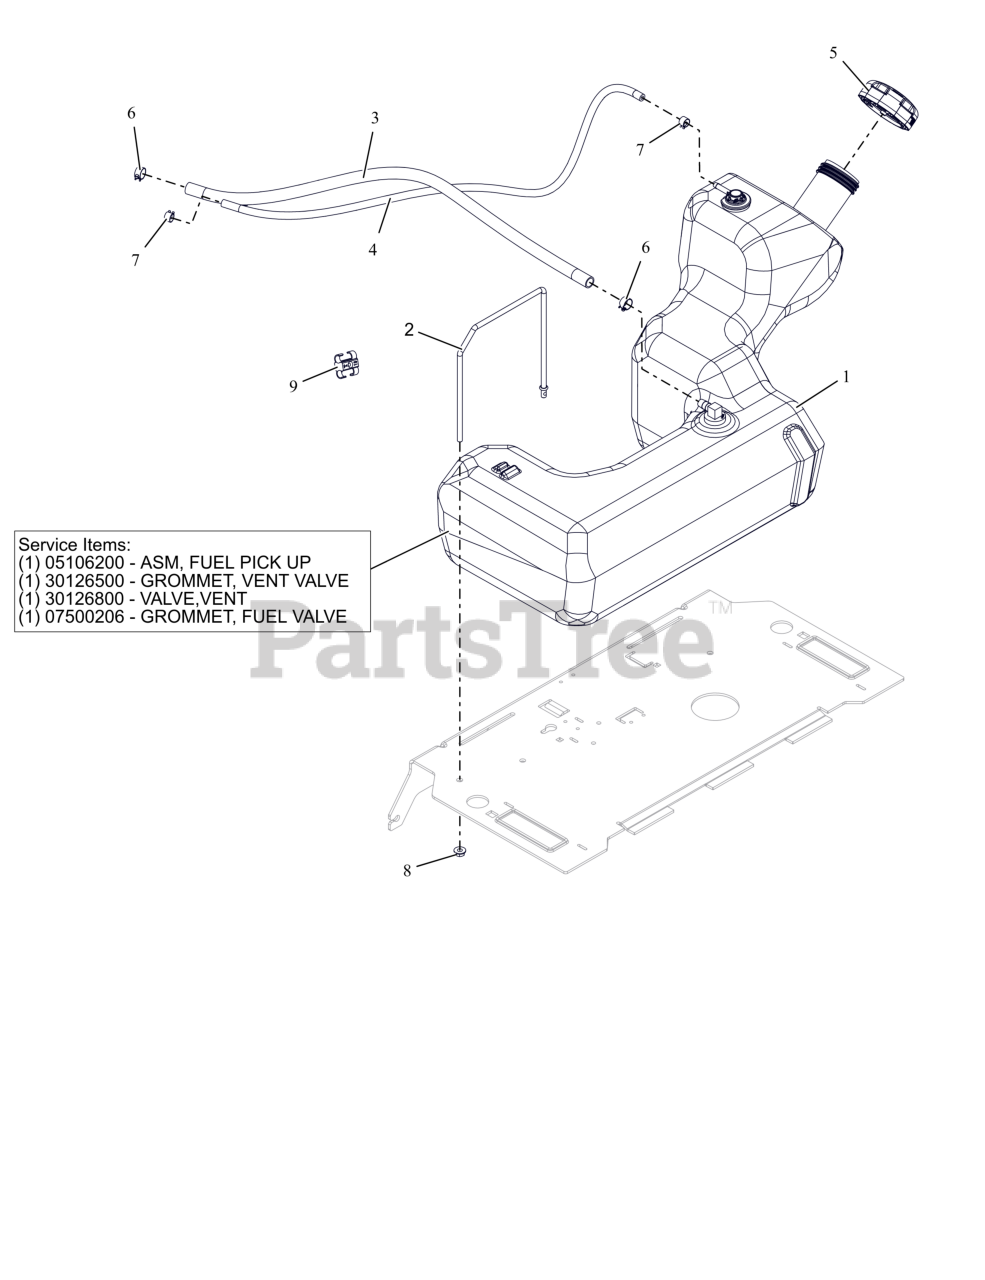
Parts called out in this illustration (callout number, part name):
1	ASM, FUEL TANK - IKON 23
1	ASM, IKON FUEL PICK-UP
1	GROMMET, VENT VALVE
1	VALVE, VENT
1	BSHG-FLG .375X1.062X.625 NITR
2	STRAP- TANK HOLD DOWN
3	HOSE, .25 LOW-PERM BULK GAS
4	HOSE, .188 30R7 BULK
5	CAP, FUEL - 2.25 RATCHET INLET VENT
6	CLAMP, FUEL LINE
7	CLAMP-HOSE, SPRING .188
8	NUT-LK-CTR-FLG .25-20 ZC120
9	CLIP, T, .38-.50
